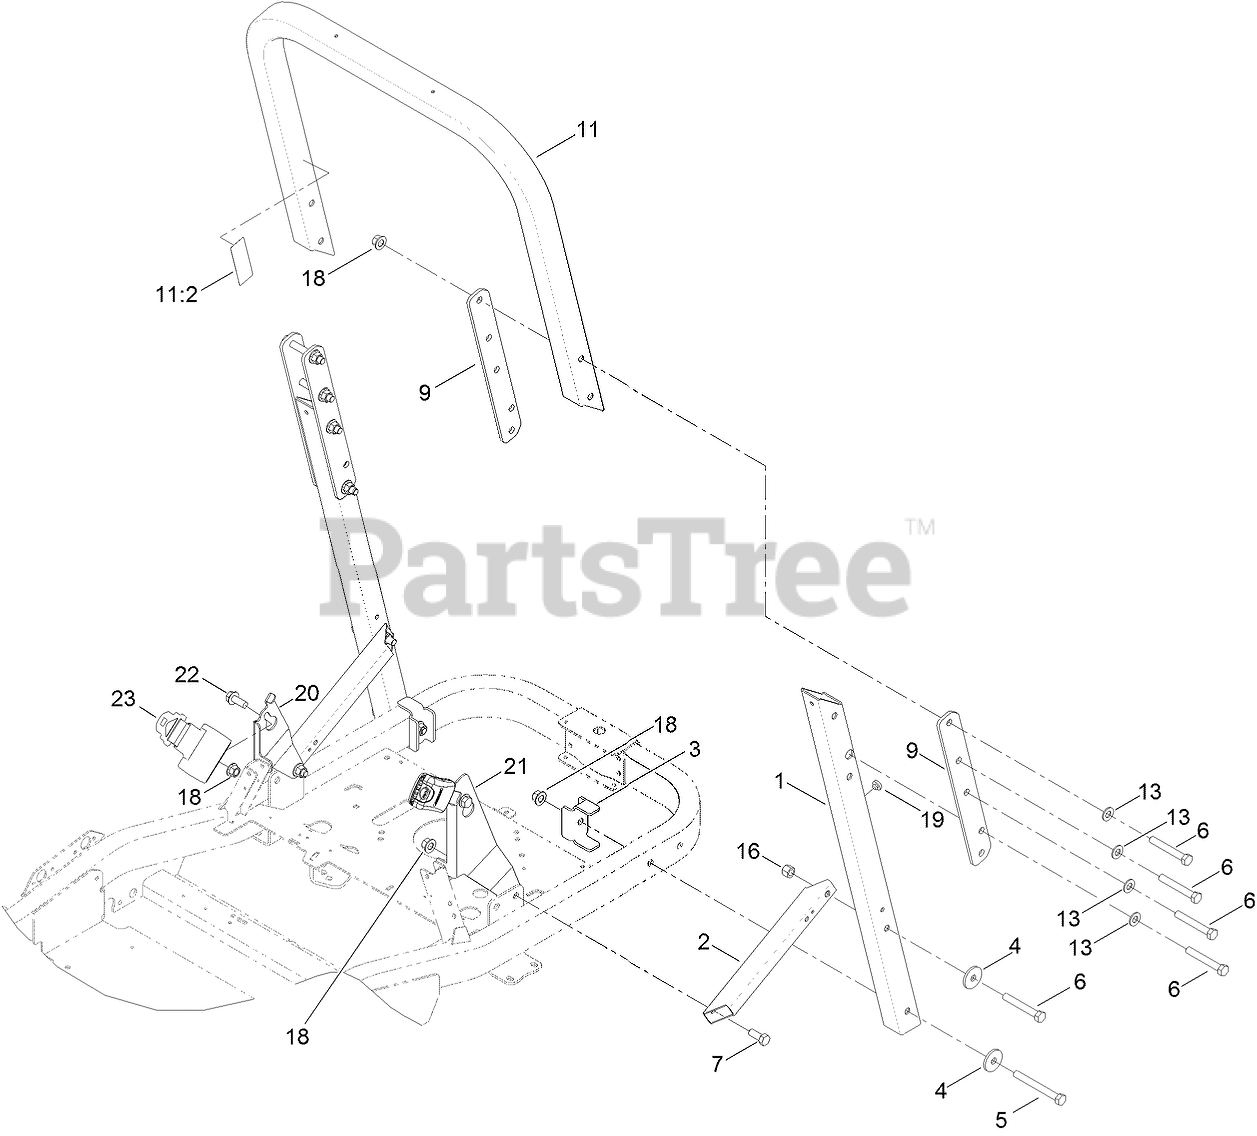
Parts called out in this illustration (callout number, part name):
1	TUBE-ROPS, LOWER
2	TUBE-SUPPORT, ROPS
3	BRACKET-REINFORCING
4	WASHER-THRUST
5	SCREW-HH
6	SCREW-HH
7	SCREW-HH
9	PLATE-ROPS
11	UPPER ROPS ASM
11:2	DECAL-ROPS, WARNING
13	WASHER-FLAT
16	NUT-HEX
18	NUT-LOCK
19	BUMPER
20	BRACKET-BELT, SEAT
21	BRACKET-BELT, SEAT
22	SCREW-HHF
23	SEAT BELT KIT
